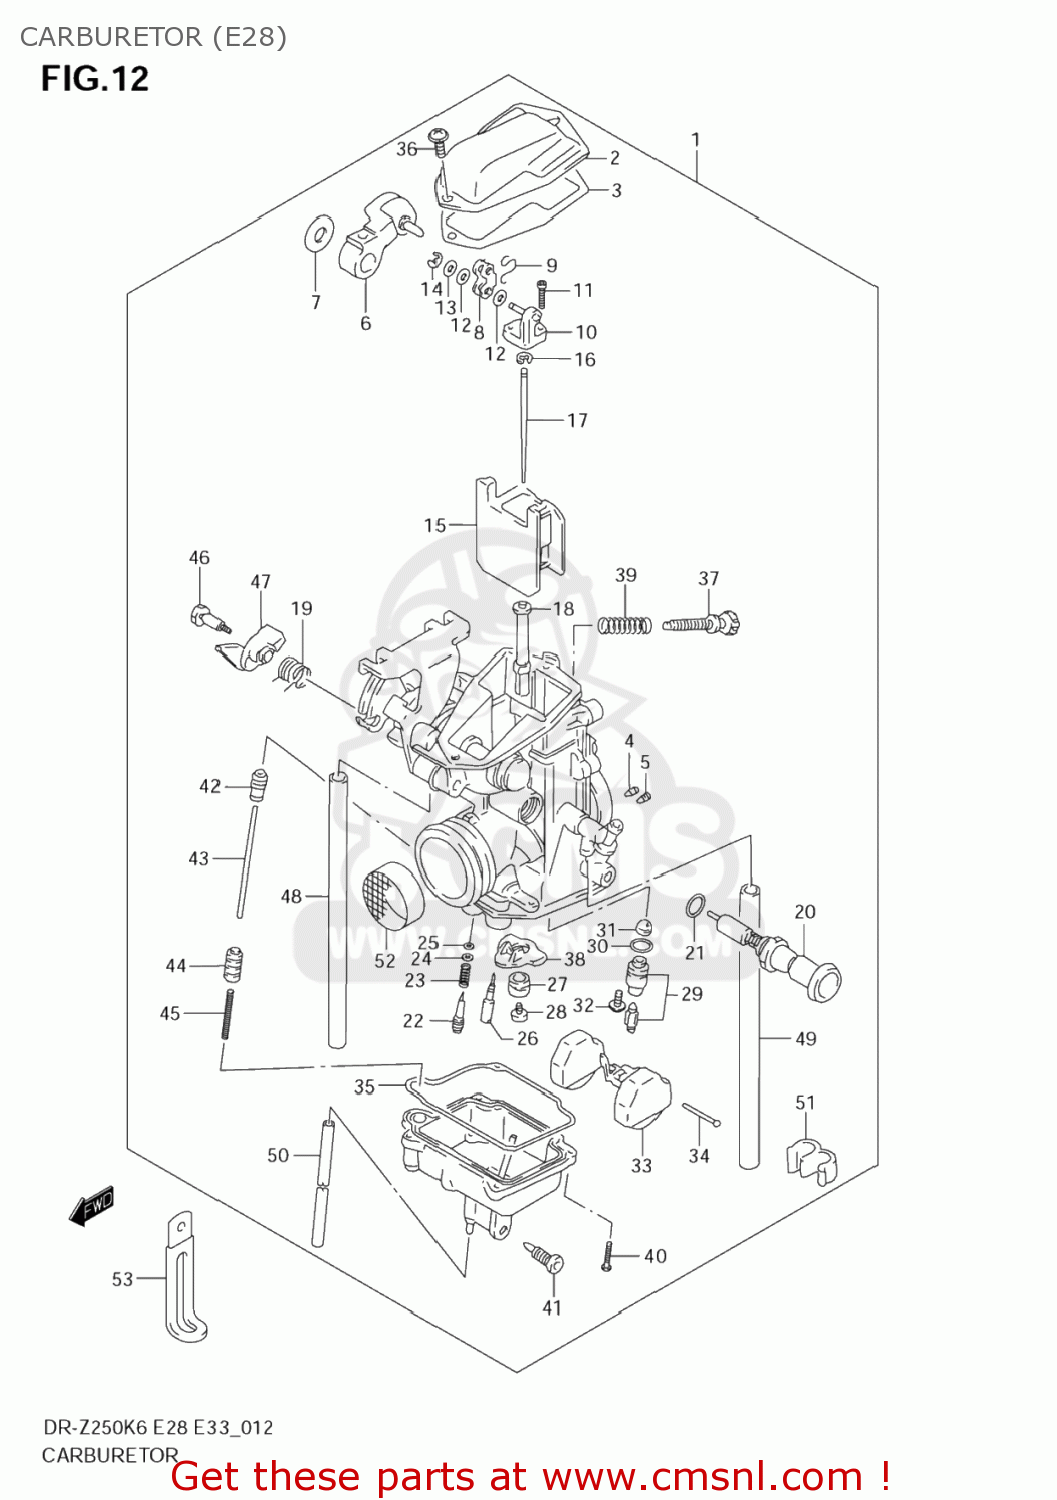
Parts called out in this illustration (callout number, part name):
1	CARBURETOR ASSY
2	COVER,TOP
3	GASKET,CARBURETOR TOP (NAS)
4	JET,AIR(1.2)
5	JET,AIR(1.6)
6	LEVER SET,THROTTLE
7	WASHER
8	PLATE
9	CLIP ASSY
10	CONNECTOR
11	SCREW
12	GASKET (NAS)
13	WASHER(4.5X8X0.5)
14	E RING
15	VALVE,PISTON
16	E RING
17	NEEDLE,JET(6FN3-3)
18	JET,NEEDLE(P-6M)
19	SPRING
20	PLUNGER ASSY
21	O RING
22	SCREW,PILOT
23	SPRING
24	WASHER
25	O RING,PILOT AIR SCREW
26	JET,PILOT(37.5)
27	RING,MAIN JET FIXING
28	JET,MAIN(127.5)
29	VALVE ASSY,NEEDLE
30	O RING,NEEDLE VALVE SEAT
31	FILTER
32	SCREW
33	FLOAT
34	PIN,FLOAT
35	O RING,FLOAT CHAMBER
36	SCREW
37	ADJUSTER
38	RING
39	SPRING
40	SCREW
41	PLUG,DRAIN
42	BOOT, ACCELE PUMP ROD
43	ROD,PLUNGER
44	PLUNGER
45	SPRING
46	BOLT
47	LEVER
48	HOSE(5X9X600)
49	HOSE(5X9X600)
50	HOSE(3X5X600)
51	CLAMP
52	NET,INTAKE
53	CLAMP(L:45)
